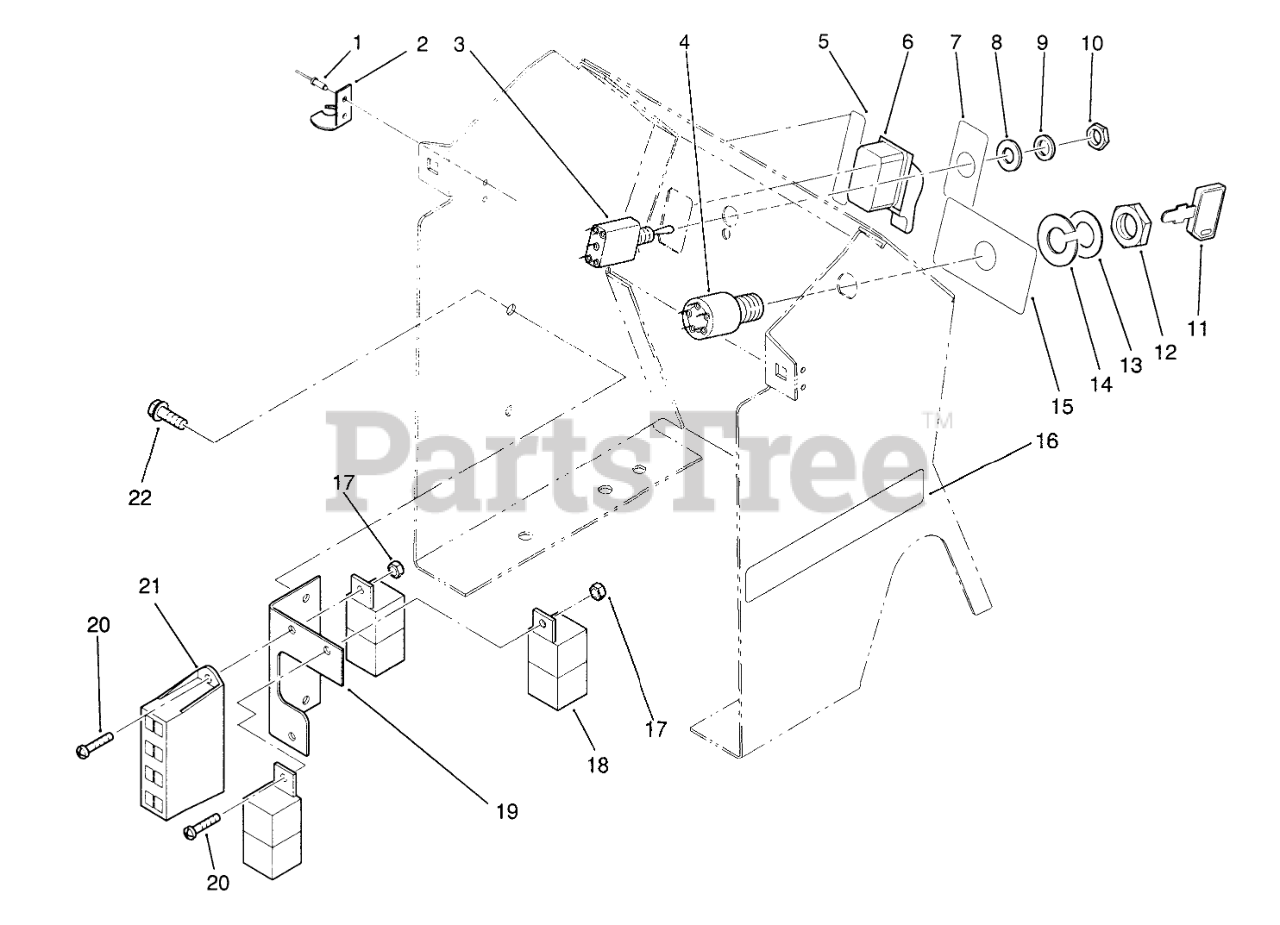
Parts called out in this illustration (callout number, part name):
1	POPRIVET 1/8X 1/8 BK
2	KEEPER-LATCH
3	Switch-Lights (Incl. Ref. #8-10)
4	Switch-Ignition, Assembly (Incl. Ref #11, 12 & 14)
5	DECAL-PTO
6	PTO-SWITCH W/COVER
7	DECAL-LIGHTS
8	TAB-WASHER
9	Washer
11	Key
13	Washer
14	LOCKWASHER
15	DECAL-IGNITION
16	DECAL-MODEL HYDRO
17	Nut
18	RELAY
19	Bracket-Holder, Fuse
20	SCREW
21	FUSE-HOLDER 4 WAY
22	TRS-1/4-20X1/2 BLACK
